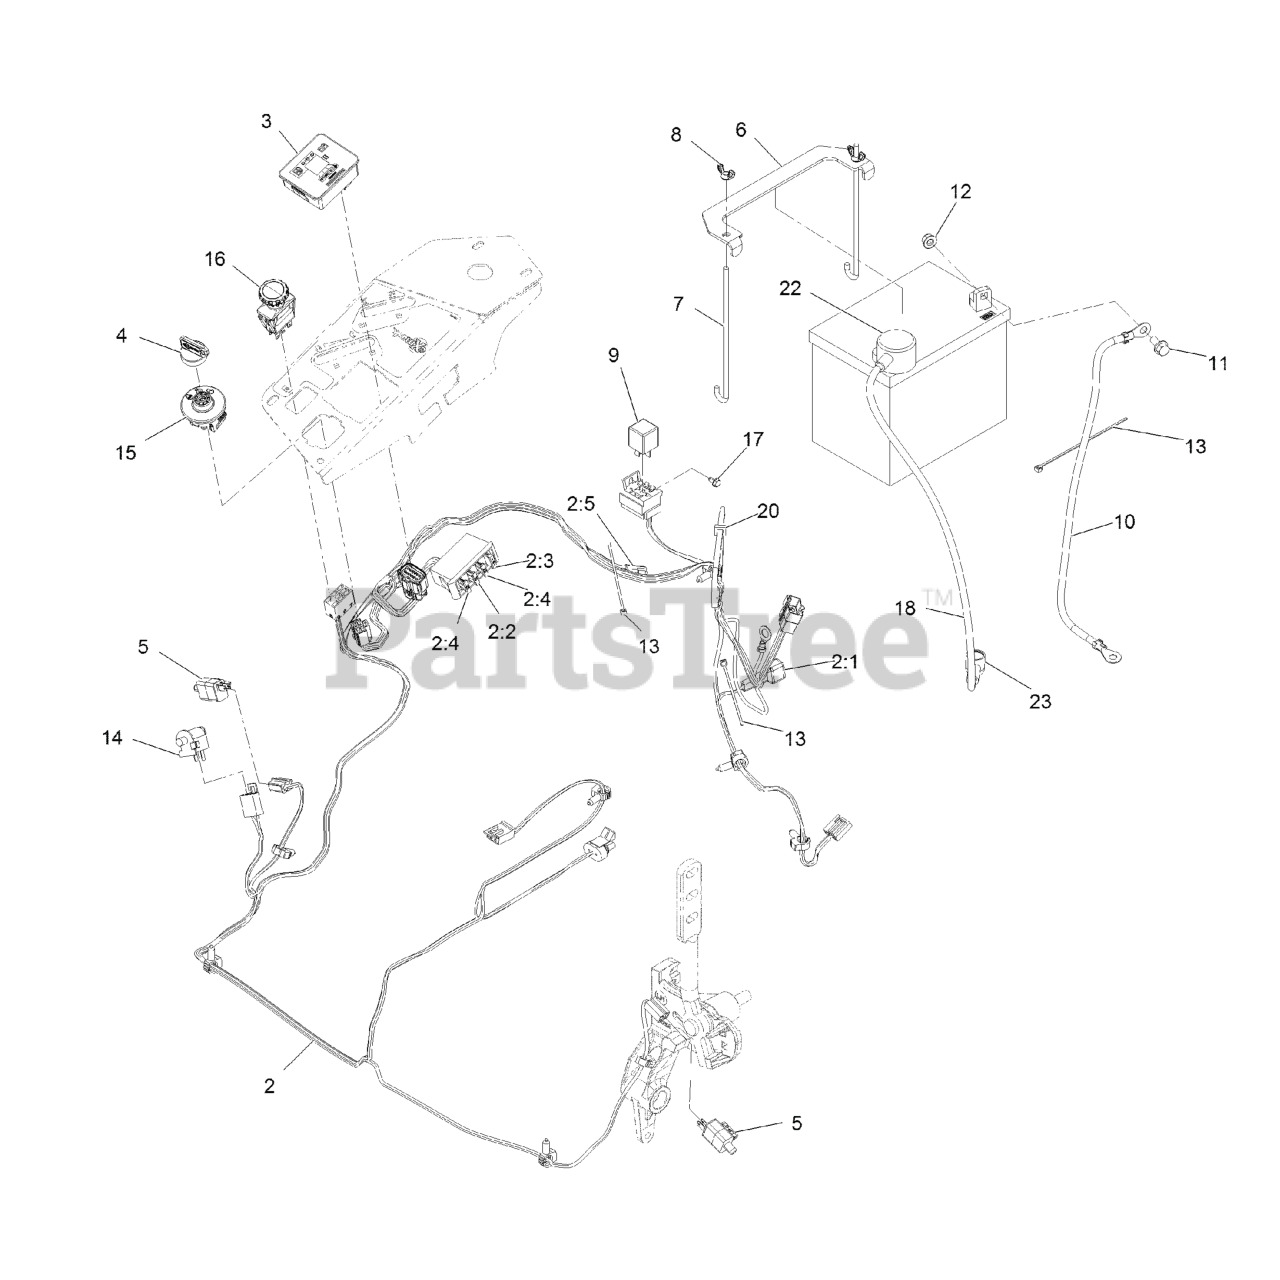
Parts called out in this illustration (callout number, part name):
2	HARNESS-WIRE, MAIN
2:2	FUSE-BLADE, 10 AMP
2:3	FUSE-BLADE, 15 AMP
2:4	FUSE-BLADE, 25 AMP
2:5	CAP-PLUG
3	FUEL/HOUR METER ASM
4	KEYS-IGNITION (SPARE PAIR
4	KEY-IGNITION
6	STRAP-TIE DOWN, BATTERY
7	BOLT-HOLDDOWN
8	WINGNUT
10	CABLE-BATTERY, NEGATIVE
11	SCREW-HHF
12	NUT-HF, NI
13	TIE-CABLE
14	SWITCH-BAIL
15	SWITCH-IGNITION
16	SWITCH-PTO, 10 AMP
17	SCREW-HWH
18	CABLE-BATTERY, POSITIVE
20	TIE-PLASTIC
22	INSULATOR-BATTERY
23	INSULATOR-SOLENOID
